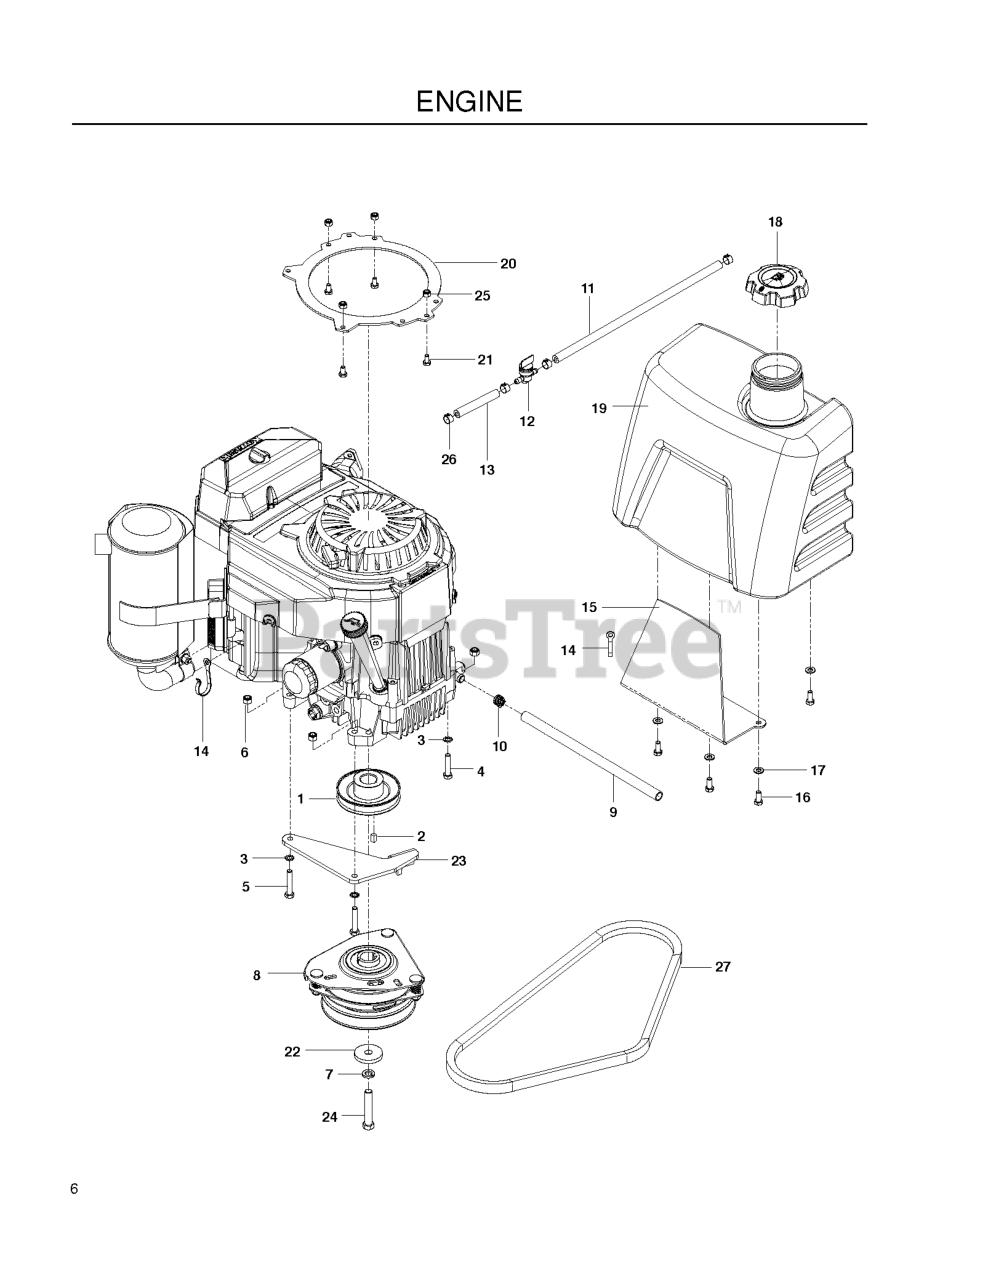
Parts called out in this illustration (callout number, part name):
1	PULLEY - ENGINE
2	SQUARE KEY - 1/4 X .5
3	WASHER 5/16 EXT STAR
4	CAPSCREW 5/16 X 1/1/2 HEX HEAD
5	HCS 5/16C X 1 3/4
6	NUT 5/16 NYLOC
7	WASHER 7/16 LOCK
8	CLUTCH 125 FT/LB
9	OIL DRAIN HOSE
10	HOSE CLAMP T-1865
11	FUEL LINE 13"
12	FUEL VALVE
13	FUEL HOSE 3.5
15	PLATE ID, ORANGE
16	HCS 5/16C X 3/4
17	FLAT WASHER 5/16 SAE
18	FUEL CAP, HTC
19	FUEL TANK
20	ADAPTER - RECOIL
21	HCS 1/4-20.
22	SPINDLE WASHER
23	CLUTCH STOP
24	BOLT 7/16F X 2 1/2
25	NUT.1/4-20.HEX.NYLOC.ZD
26	HOSE CLAMP
27	V-BELT PUMP DRIVE
